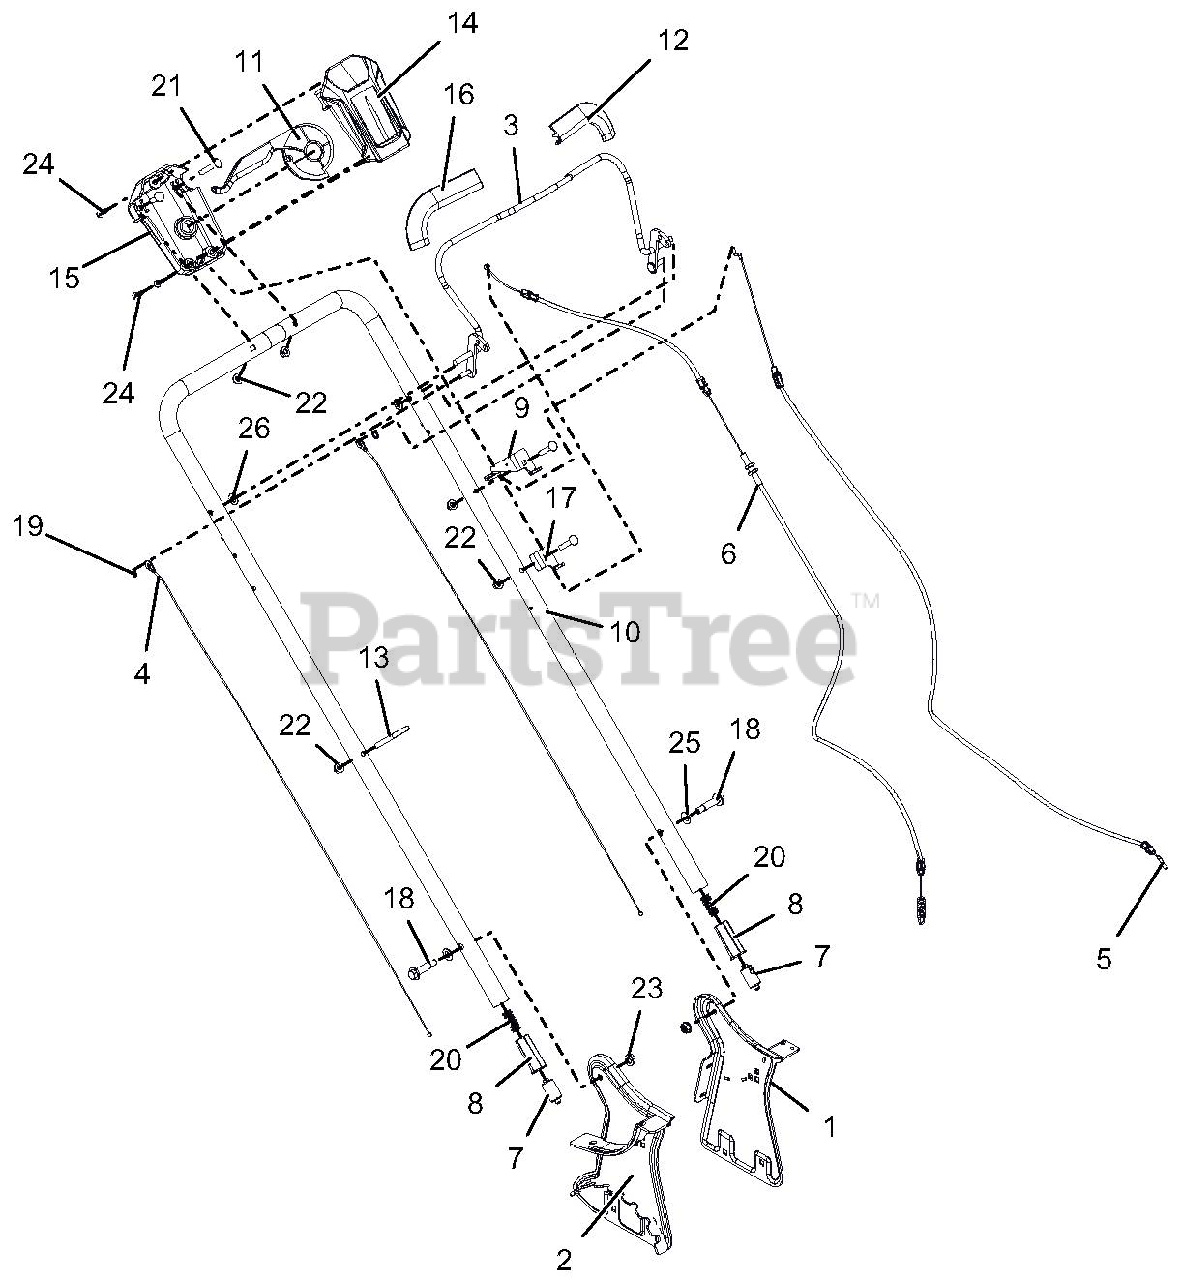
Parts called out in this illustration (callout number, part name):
1	SUPPORT, LH HANDLEBAR
2	SUPPORT, RH HANDLEBAR
3	WLDMT, OPC BAIL
4	CABLE, LM HANDLE ADJUST
5	CABLE, OPC, RAZOR LM
6	CABLE, DRIVE CONTROL
7	PLUNGER, HANDLEBAR LOCKING
8	INSERT, HANDLEBAR ADJUST
9	BRKT, CABLE ANCHOR
10	HANDLEBAR, LM
11	HANDLE, DRIVE CONTROL
12	GUARD, FINGER - LH
13	HOLDER, RECOIL CORD
14	HOUSING, UPPER DRIVE CONTROL
15	HOUSING, LOWER DRIVE CONTROL
16	HAND GRIP W/ DECAL
17	BRKT, CABLE - DRIVE
18	BLT-SHLDR, .50X1.15X.312-18GR5
19	RG-RTNG-EXT .250X.010
20	SPRING, COMPRESSION
21	@BLT-RDHDSQNK .25-20X1.50 G5YZ
22	@NUT-LK-TOP-FLG .25-20 YWZC
23	@NUT-LK-TOP-FLG .31-18 YWZC
24	SCR-TAP 12-14X.75PLSTITE @BLZC
25	WSHR,.385X.745X.030 STL YWZC
26	@WSHR-FL-STL.344X.688X.065YWZC
